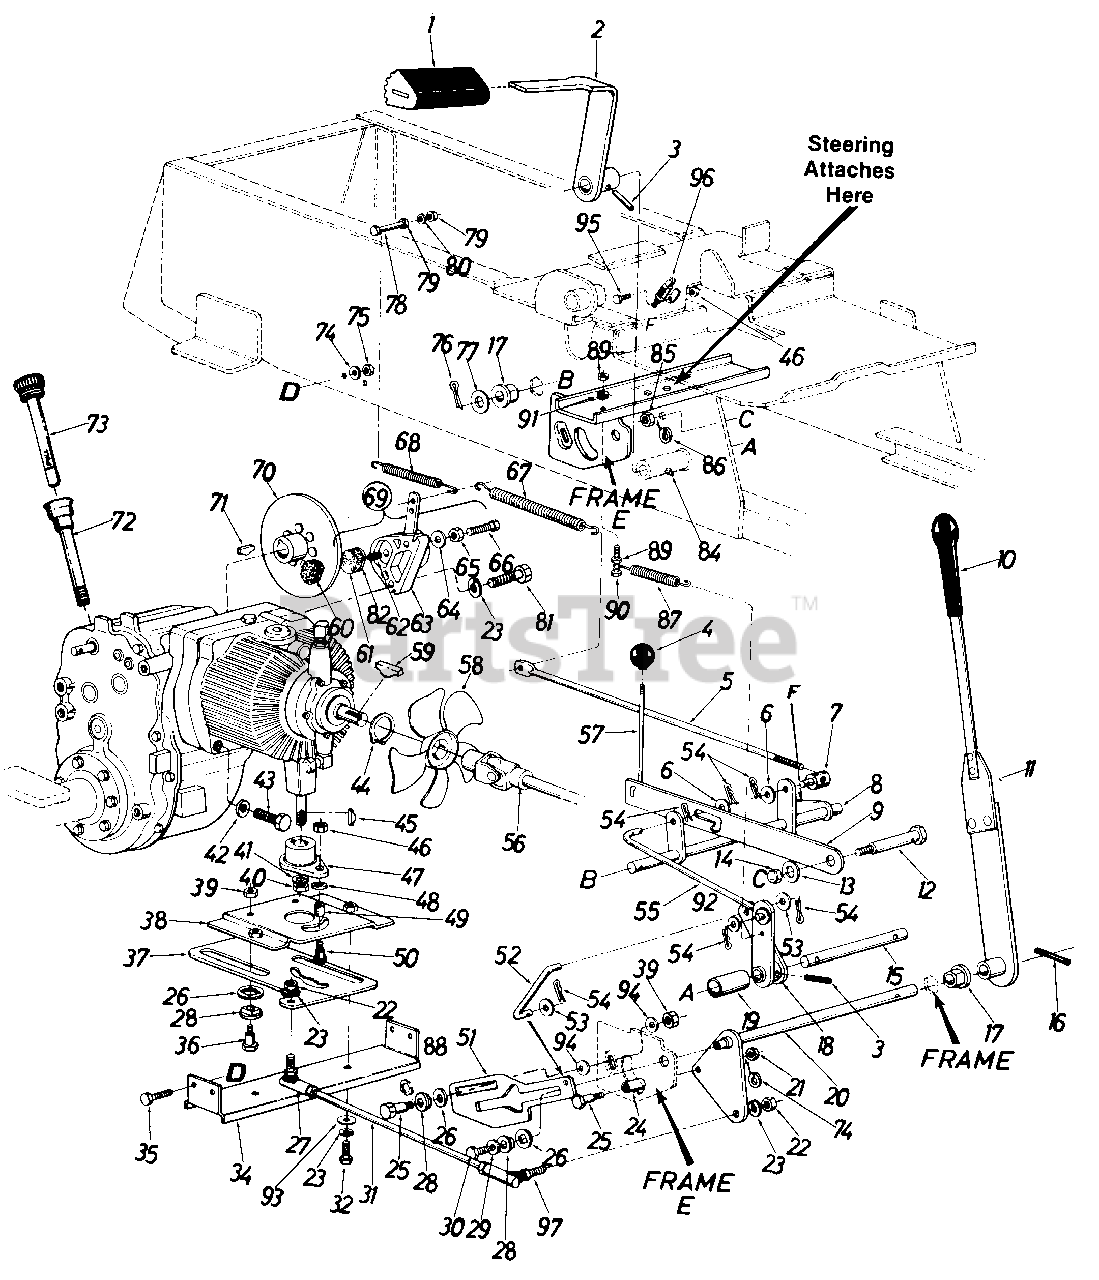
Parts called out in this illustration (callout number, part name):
4	Ball Knob Brake
6	Fl-Wash. .375" I.D. x 1.00" O.D. x .030
7	Ferrule
8	Brake Transfer Shaft Ass'y.
9	Parking Brake Cam
11	Control Arm Ass'y. Comp.
12	Shld. Scr. .62 Dia. x 2.75" Lg.
13	Fl-Wash. .460 I.D. x 1.24 O.D. x .06
14	Push Speed Nut for .625 Dia. Shaft
15	Brake Pivot Shaft
16	Spring Pin Spiral 1/4" Dia. x 1.50" Lg.
17	Hex Flange Brg. Plastic .62 I.D.
18	Brake Hub Ass'y.
20	Control Handle Ass'y.
21	Hex Cent. L-Nut 5/16-18 Thd.
22	Hex Nut 3/8-24 Thd.
23	L-Wash. 3/8" Scr.'
25	Shoulder Bolt
26	Fl-Wash. .63 Sq. Hole x 1.25" O.D.
27	Ball Joint Ass'y. 318-24 Th d . L. H .
29	Fl-Wash. .312 I.D. x .88 O.D.
30	Hex Ins. Scr. 5/16-18 x 1.00" Lg .
31	Tie Rod
32	Hex Scr. 3/8-16 x .75" Lg.
34	Support Channel
35	Hex Scr. 5/16-18 x .75" Lg.
36	Shld. Scr. .437" Dia. x .350
38	Slide Mtg. Plate Ass'y.
39	Hex Cent. L-Nut 5/16-18 Thd.
40	Hex Nut 1/2-13 Thd.
41	L-Wash. 1/2" Scr.
42	Fl-Wash. .385 I.D. x .87 0 O.D. x .060
43	Socket Hd. Scr. 3/8-16 x 2.75" Lg.
45	#5 Hi-Pro Key 1/8" x 5/8" Dia.
46	Hex Cent. L-Nut 1/4-20 Thd.
47	Pintle Plate Ass'y.
48	Fl-Wash. .281 I.D. x .50 O.D. x .063
49	Needle Brg. .31" I.D. x .50" O.D. x .437" Lg.
50	Shld. Scr. .31 Dia. x .500
51	Neutral Control Slide
52	Neutral Control Rod
53	Fl-Wash. .32 I.D. x .630 O.D. x .063
54	Hairpin Cotter
55	Brake Link Rod Ass'y.
56	Universal Joint Ass'y. Comp.
57	Parking Brake Link
58	Fan Ass'y.
59	#61 Hi-Pro Key 3/16 x 5/8" Dia.
60	Lining Brake
61	Lining Brake
63	Housing with Lever and Pin
64	Washer
65	Nut
66	Adjustment Pin
67	Extension Spring .59 O.D. x 6.5" Lg.
68	Extension Spring
69	Disc Brake Ass'y. Comp.
70	Brake Disc Ass'y.
71	Hi-Pro Key 3/16 x 314" Dia.
72	Dipstick Tube Ass'y.
73	Dipstick Ass'y.
74	L-Wash. 5/16" Scr.
75	Hex Nut 5/16-18 Thd.
76	Cotter Pin 1/8" Dia. x 1.00" Lg.
77	Fl-Wash. .635" I.D. x 1.00 O.D. x .120 Thk.
78	Hex Scr. 1/4-20 x 2.50" Lg.
79	Hex Nut 1/4-20 Thd.
80	L-Wash. 1/4" Scr.
81	Hex Scr 3/8-16 x 1.25" Lg.
82	Backing Plate
84	Grease Fitting
85	Hex Nut 7/16-20 Thd.
86	L-Wash. 7/16" Scr.
87	Extension Spring
88	Wave Wash.
89	Hex Nut 1/4-20 Thd.
90	Hex Scr. 1/4-20 x 1.25" Lg.
91	L-Wash. 1/4" Scr.
92	Fl-Wash.
93	Fl-Wash. .38 I.D. x 1.25 O.D.
95	Hex Scr. 1/4-20 x 1/2 Lg.
96	Safety Switch
97	Ball Joint Ass'y. 318-24 Thd. R. H .
